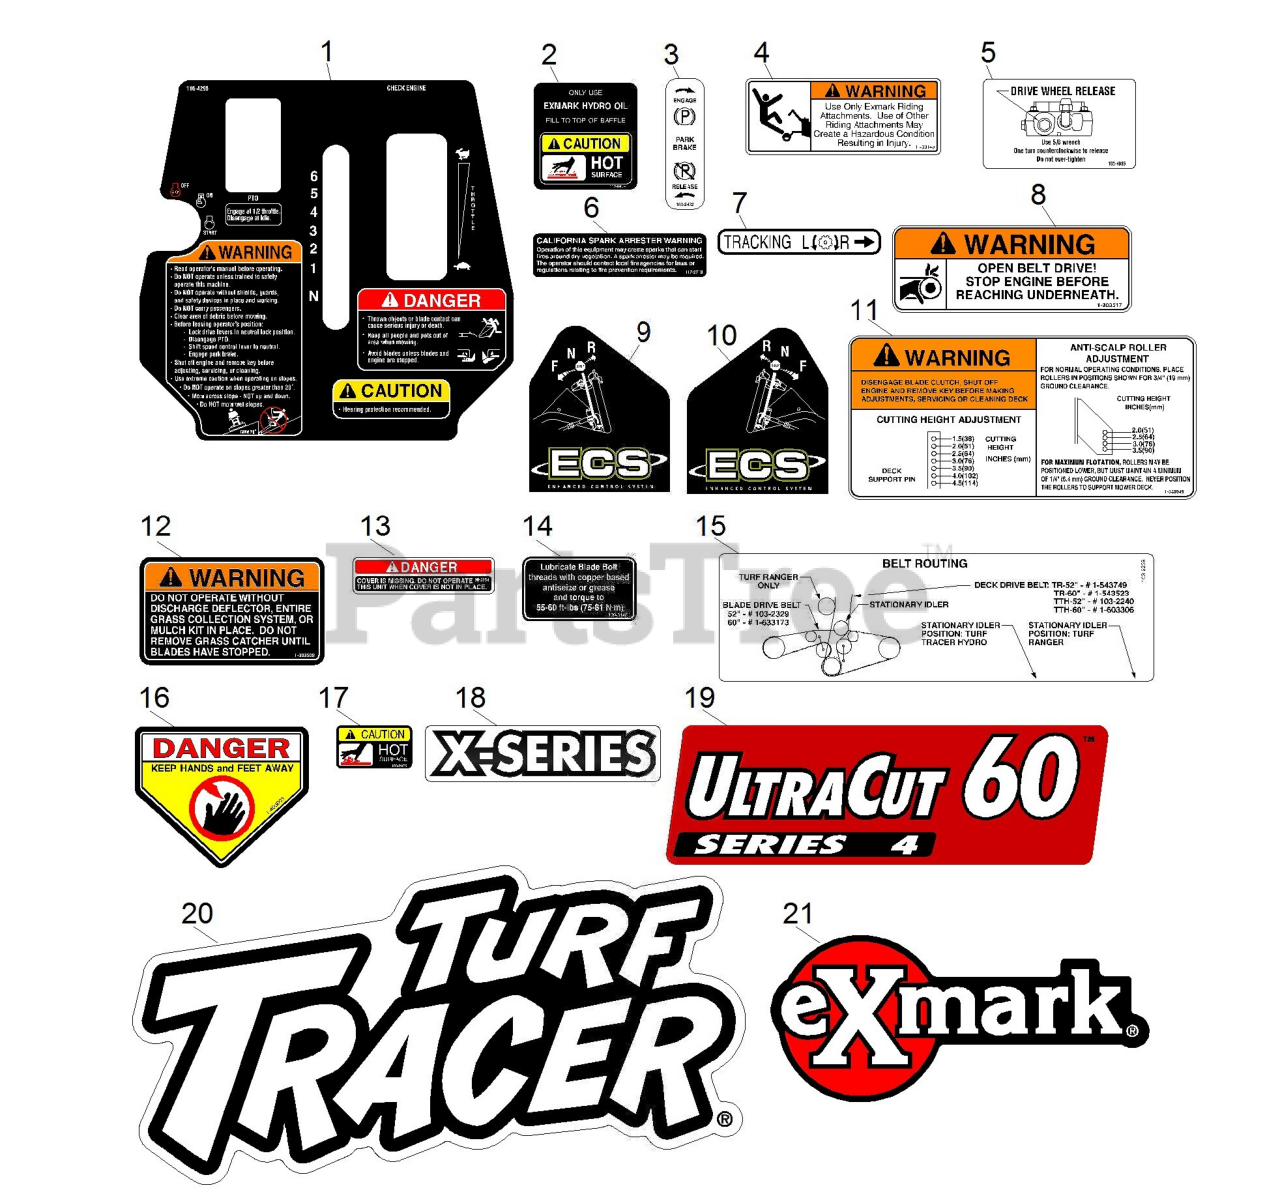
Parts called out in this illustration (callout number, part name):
1	DECAL,CONSOLE TTX
2	DECAL-HYDRAULIC TANK
3	DECAL,PARKING BRAKE
4	DECAL,SULKY WARNING
5	DECAL,DRIVE RELEASE
6	DECAL-ARRESTER, SPARK
7	DECAL,TRACKING ADJUST
8	DECAL,BELT DRIVE
9	DECAL,LH ECS INSTRUCTION
10	DECAL,RH ECS INSTRUCTION
11	DECAL,ANTI SCALP
12	DECAL-WARNING, DISCHARGE
13	DECAL-COVER, MISSING
14	DECAL,BOLT TORQUE
15	DECAL,BELT ROUTING
16	DECAL-DANGER
17	DECAL-CAUTION
18	DECAL-X-SERIES
19	DECAL,ULTRACUT 60 SERIES
20	DECAL,TTH MODEL
21	DECAL,EXMARK LOGO
